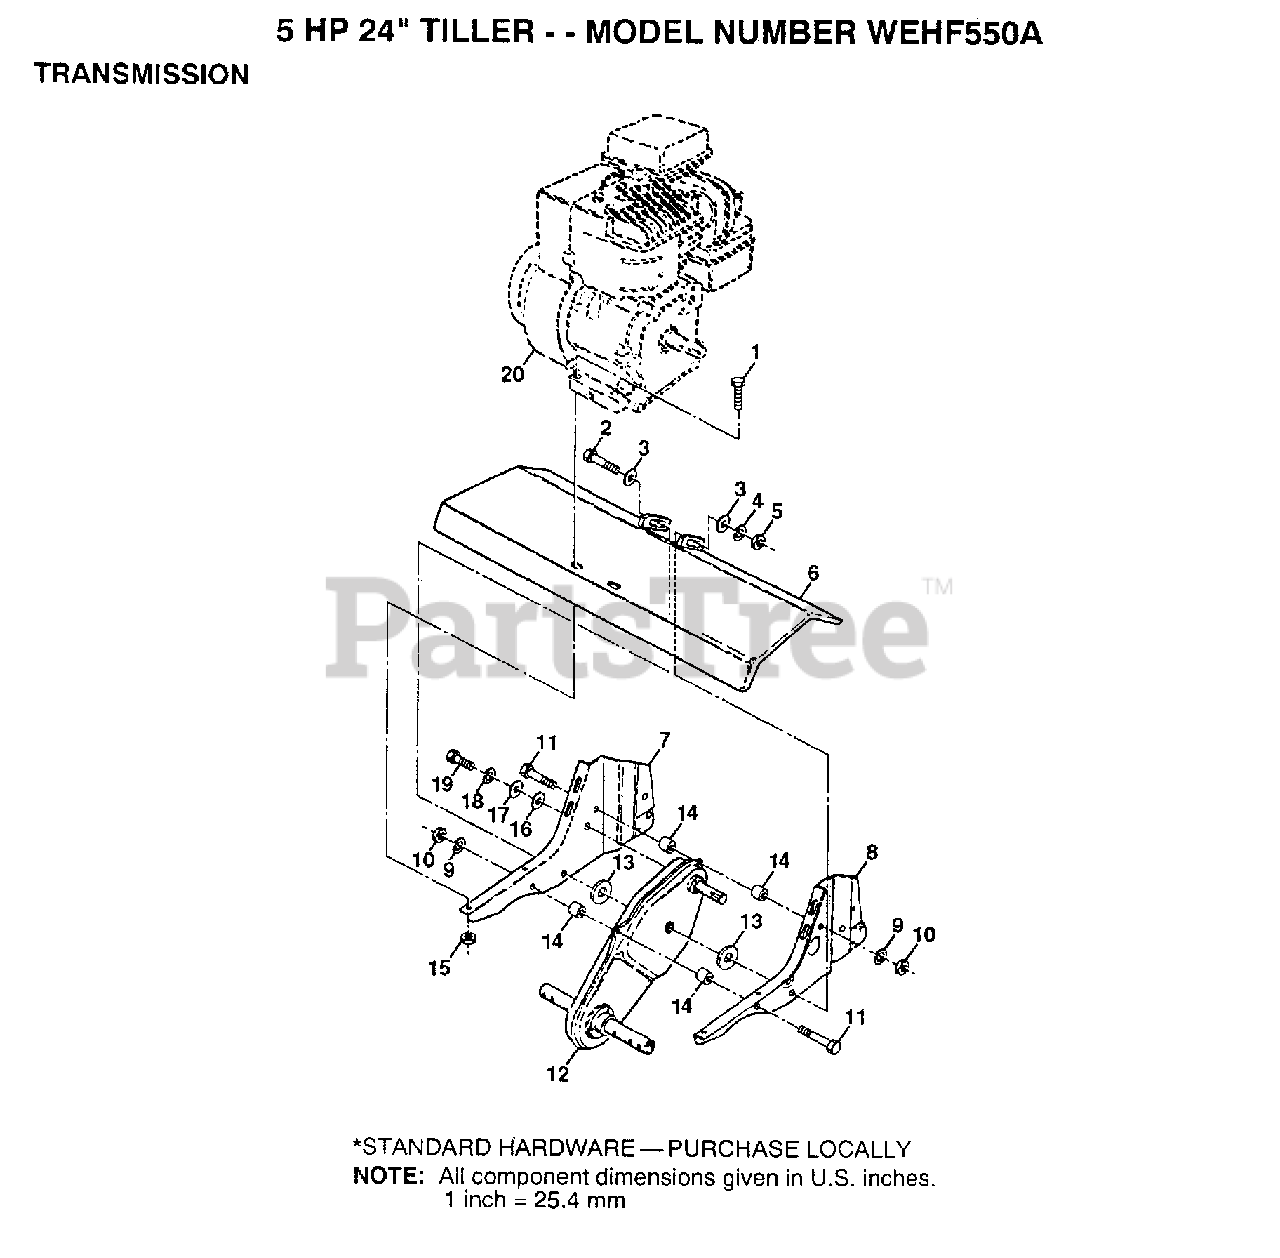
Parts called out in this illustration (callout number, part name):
1	BOLT.HEX.5/16-1.5
2	BOLT.3/8-24X3.75
3	WASHER
4	LOCKWASHER
5	GRIPCO NUT
8	BRACKET.ENG.LH.
9	LOCKWASHER
10	NUT.HEX.5/16-18
14	SPLIT SPACER RT
16	WASHER
17	WASHER
18	LOCKWASHER
19	BOLT
